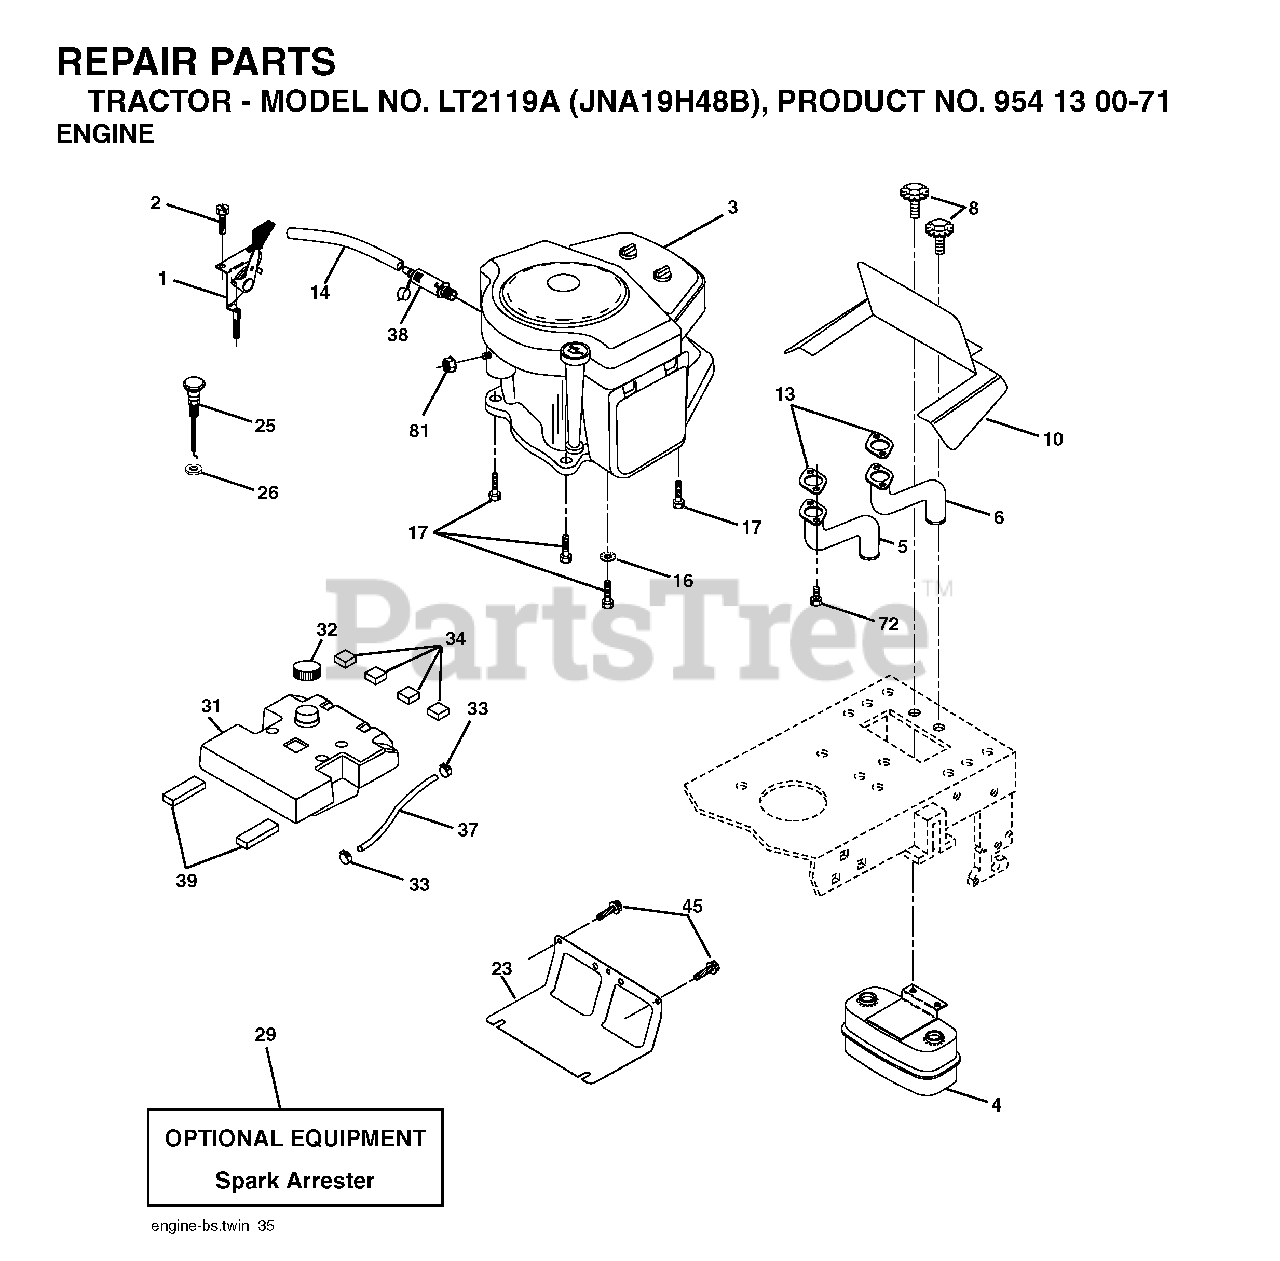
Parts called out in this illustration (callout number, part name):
1	CONTROL, THROTTLE
2	SCREW
4	MUFFLER.TWIN.CYL.LOW.TONE
5	EXHAUST TUBE RH
6	TUBE MANIFOLD LH
8	BOLT, 5/16-18 X 1 3/4
10	SHIELD.BROWNING.B&S
13	GASKET.MUFFLER
14	TUBE, DRAIN OIL ASM.
16	LOCKWASHER
23	SHEILD.BROWNING.DBR.GUARD
25	CONTROL, CHOKE
26	NUT KEPS 3/8 - 24 UNF
29	ARRESTER SPARK (OPTIONAL)
31	TANK.FUEL(3.5.GAL)
32	FUEL CAP
33	HOSE CLAMP
34	PAD-SPACER LT
38	PLUG DRAIN OIL EASY
39	PAD IDLER TI
45	SCREW, 3/8-16X3/4
72	SCREW.SOCKET.HEAD.5/16-18
81	NUT
